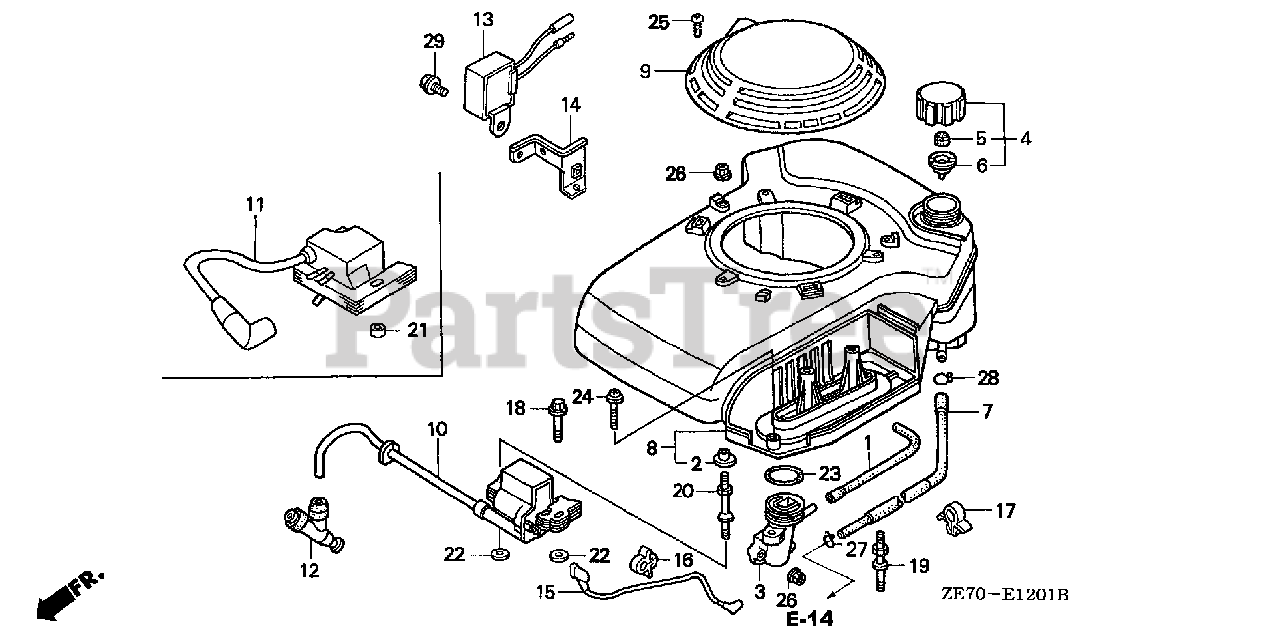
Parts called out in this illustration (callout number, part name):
1	TUBE, BREATHER
2	COLLAR, AIR CLEANER (TOYO ROKI)
3	ELBOW, AIR CLEANER
4	CAP ASSY., FUEL TANK
5	SPONGE, FUEL CAP BREATHER
6	GASKET, FUEL CAP
7	TUBE ASSY., FUEL TANK
8	COVER, FAN *NH1* (BRAKE) (BLACK)
8	COVER, FAN *R280* (BRAKE) (POWER RED)
9	HOOD, FAN COVER *NH1* (GRAINED FINISH) (BLACK)
9	HOOD, FAN COVER *R280* (GRAINED FINISH) (POWER RED)
11	COIL ASSY., IGNITION
16	HOLDER, STOP SWITCH WIRE
17	CLAMP, BRAKE PIPE (GRAY)
18	BOLT, FLANGE (6X28) (CT200)
19	BOLT, STUD (BRAKE)
20	BOLT, STUD (IGNITION COIL)
21	COLLAR, SPECIAL
23	O-RING (33.3X3.5)
24	SCREW-WASHER (6X35)
25	SCREW, TAPPING (4X20)
26	NUT, FLANGE (6MM)
27	CLIP, TUBE (B8)
28	CLIP, TUBE (B10)
28	CLIP, TUBE (C9)
